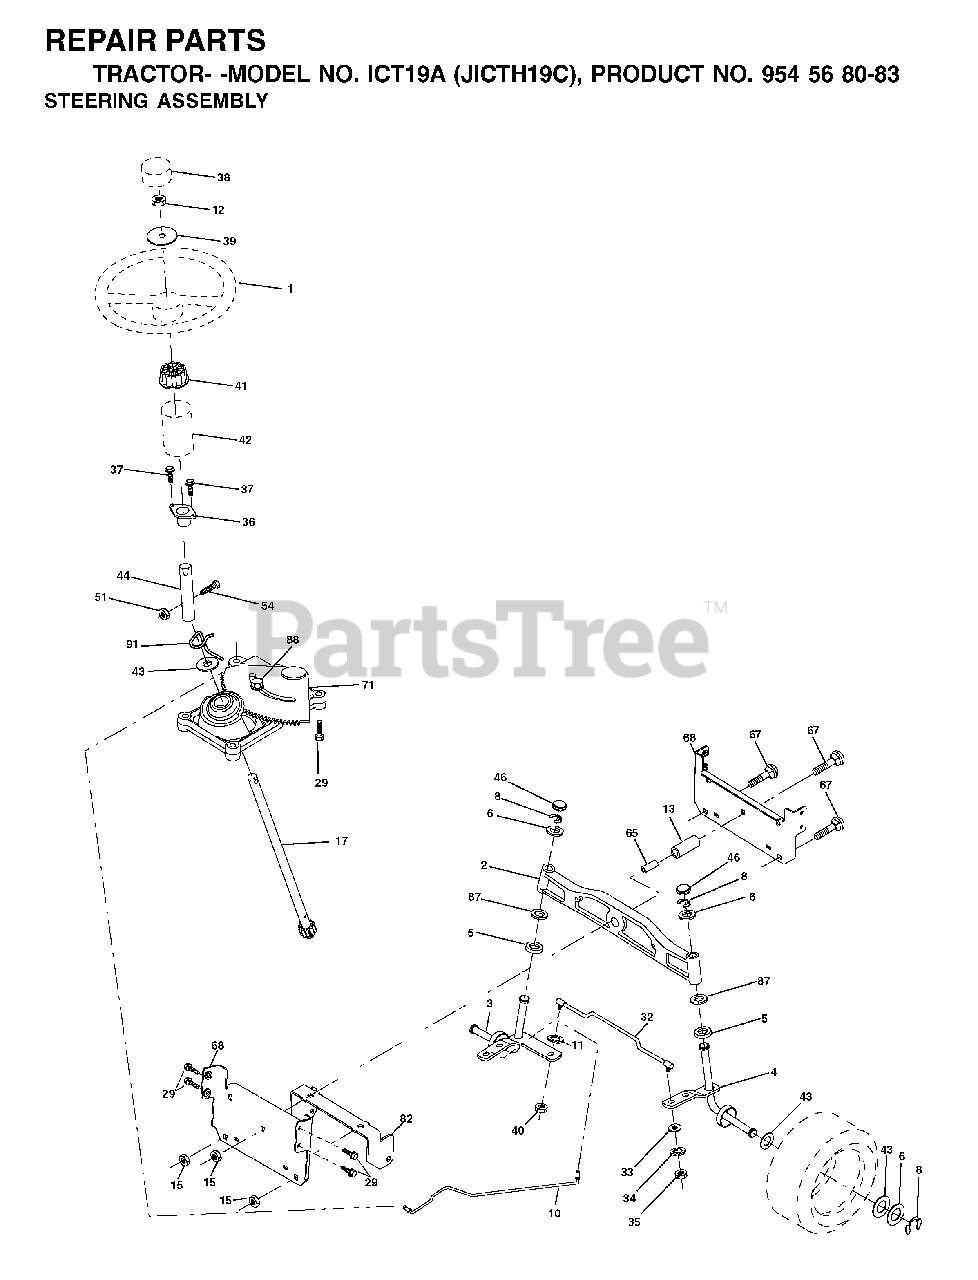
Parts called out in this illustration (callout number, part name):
2	AXLE ASM
3	SPINDLE.ASM.LH.15"TIRES
4	SPINDLE.ASM.RH.15"TIRES
8	RING CLIP
10	DRAGLINK.15".TIRES.2001
11	WASHER, LOCK 3/8
12	NUT.HEX.1/2-20
13	TUBE, PIVOT AXLE
15	NUT
17	SHAFT ASM, STEERING
29	SCREW 3/8-16X3/4
33	WASHER M
34	LOCKWASHER
35	NUT, CROWNLOCK
36	BUSHING, STEERING
40	GRIPCO NUT
41	STEERING WHEEL ADAPTOR
42	BOOT.STEERING.SHAFT.BLACK
44	EXT, STEERING SHAFT
46	CAP.SPINDLE
51	CROWN LOCKNUT
65	SPACER BRACE AXLE
67	BOLT
68	BRACE.AXLE.15"TIRES
71	STEERING ASM
82	BRACKET
87	WASHER, FLAT .781 X 1 1/2"
88	BOLT, SHOULDER 7/16-20
91	CLIP.STEERING
